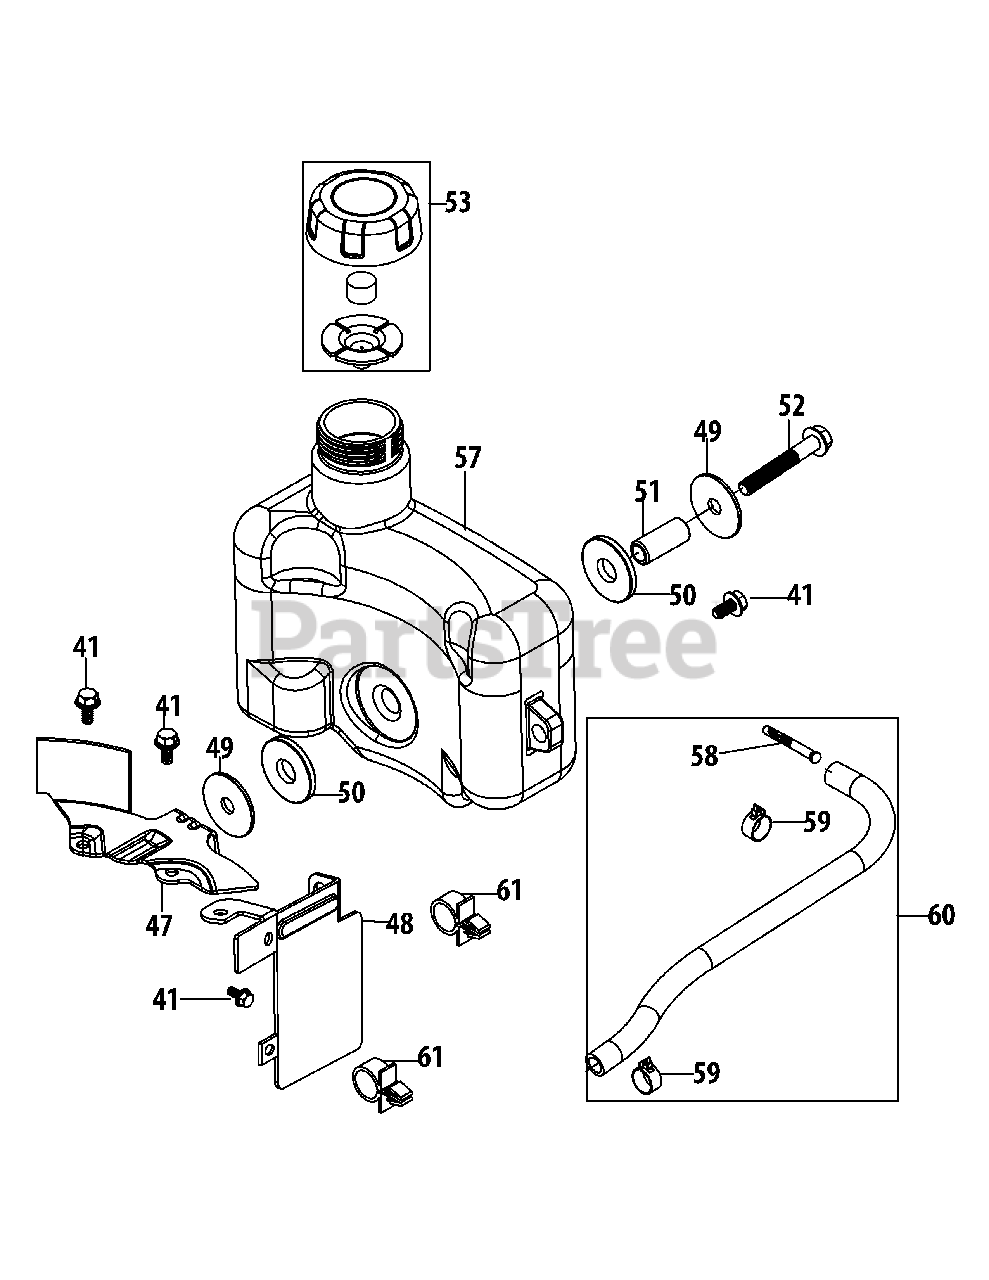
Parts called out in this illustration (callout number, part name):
41	Bolt M6X14 Multi-Purpose
47	Fuel Tank Bottom Bracket
48	Fuel Tank / Label Bracket
49	Fuel Tank Washer
50	Rubber Bushing
51	Fuel Tank Bushing
52	Bolt M8X50 Fuel Tank
53	Fuel Cap Assembly
57	Fuel Tank Assembly
58	Fuel Filter
59	Fuel Hose Clamp
60	Fuel Hose Kit
61	Plastic Support Clamp
